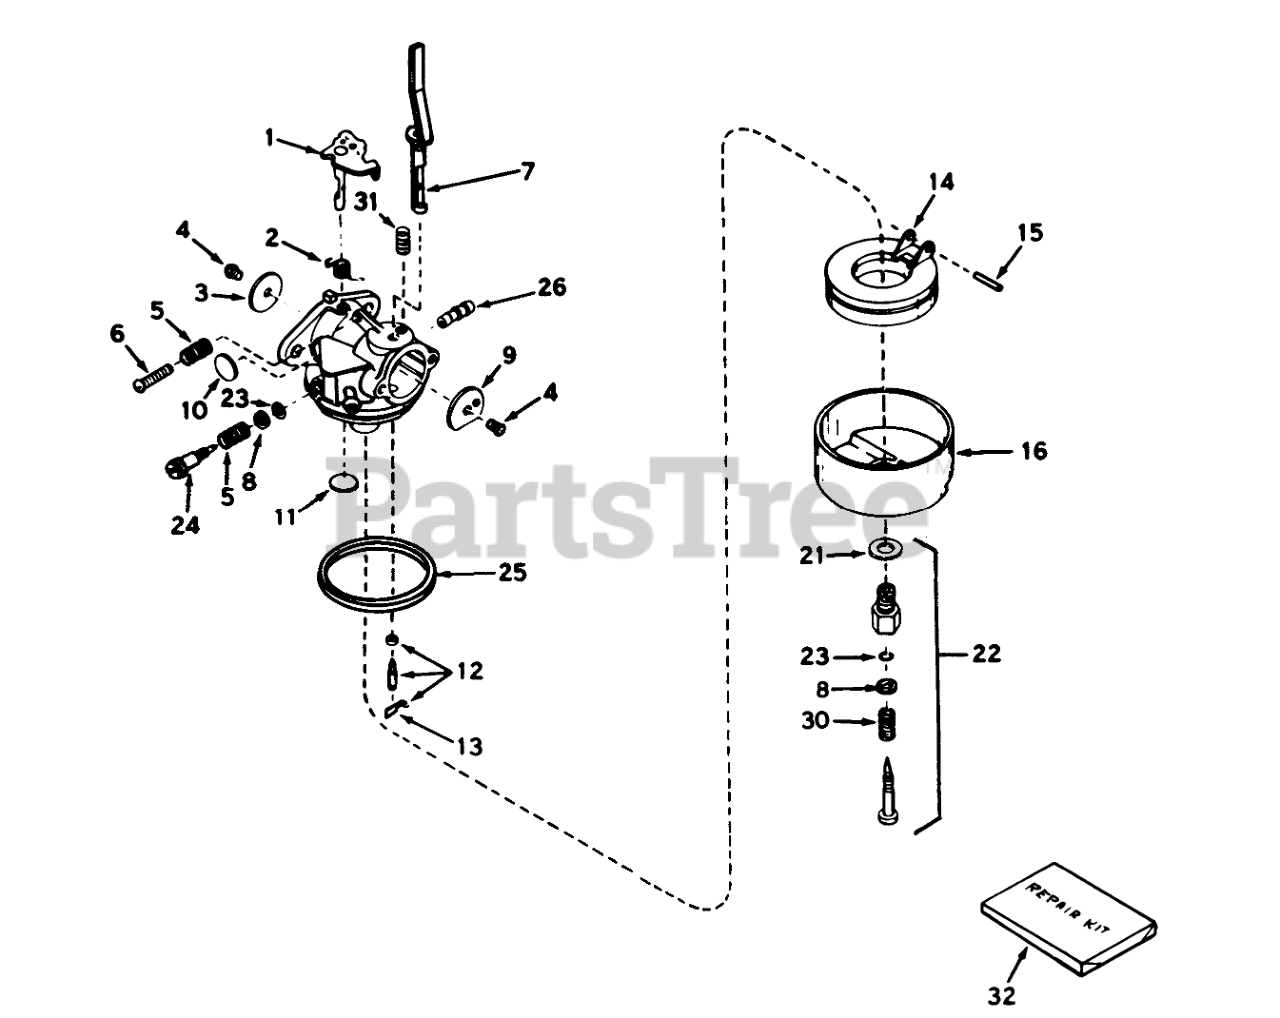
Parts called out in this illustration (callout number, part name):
1	Shaft/Lever-Throttle
2	Spring, Return
3	Shutter-Throttle
4	Screw-Shutter
5	Spring-Tension
6	Screw-Throttle Crack Screw / Idle Speed
7	Shaft & Lever Assy., Choke
9	Shutter-choke
10	Plug-Welch, Idle Mixture Well
11	Plug-Welch, Atmospheric Vent
12	Inlet Needle, Seat & Clip Assy. (Incl. Ref. #13)
13	Clip-Spring
14	Float
15	Shaft-Float
16	Bowl-Float (no drain)
21	Washer-Bowl Nut
22	Adjustment Screw Assy., Main (Incl. Ref. #8, 21, 23 & 30)
23	"O"Ring
24	Screw, Idle Adj.
25	O Ring-Bowl, Float
26	Fuel Fitting
31	Spring-Positioning, Choke
32	Kit-Repair
